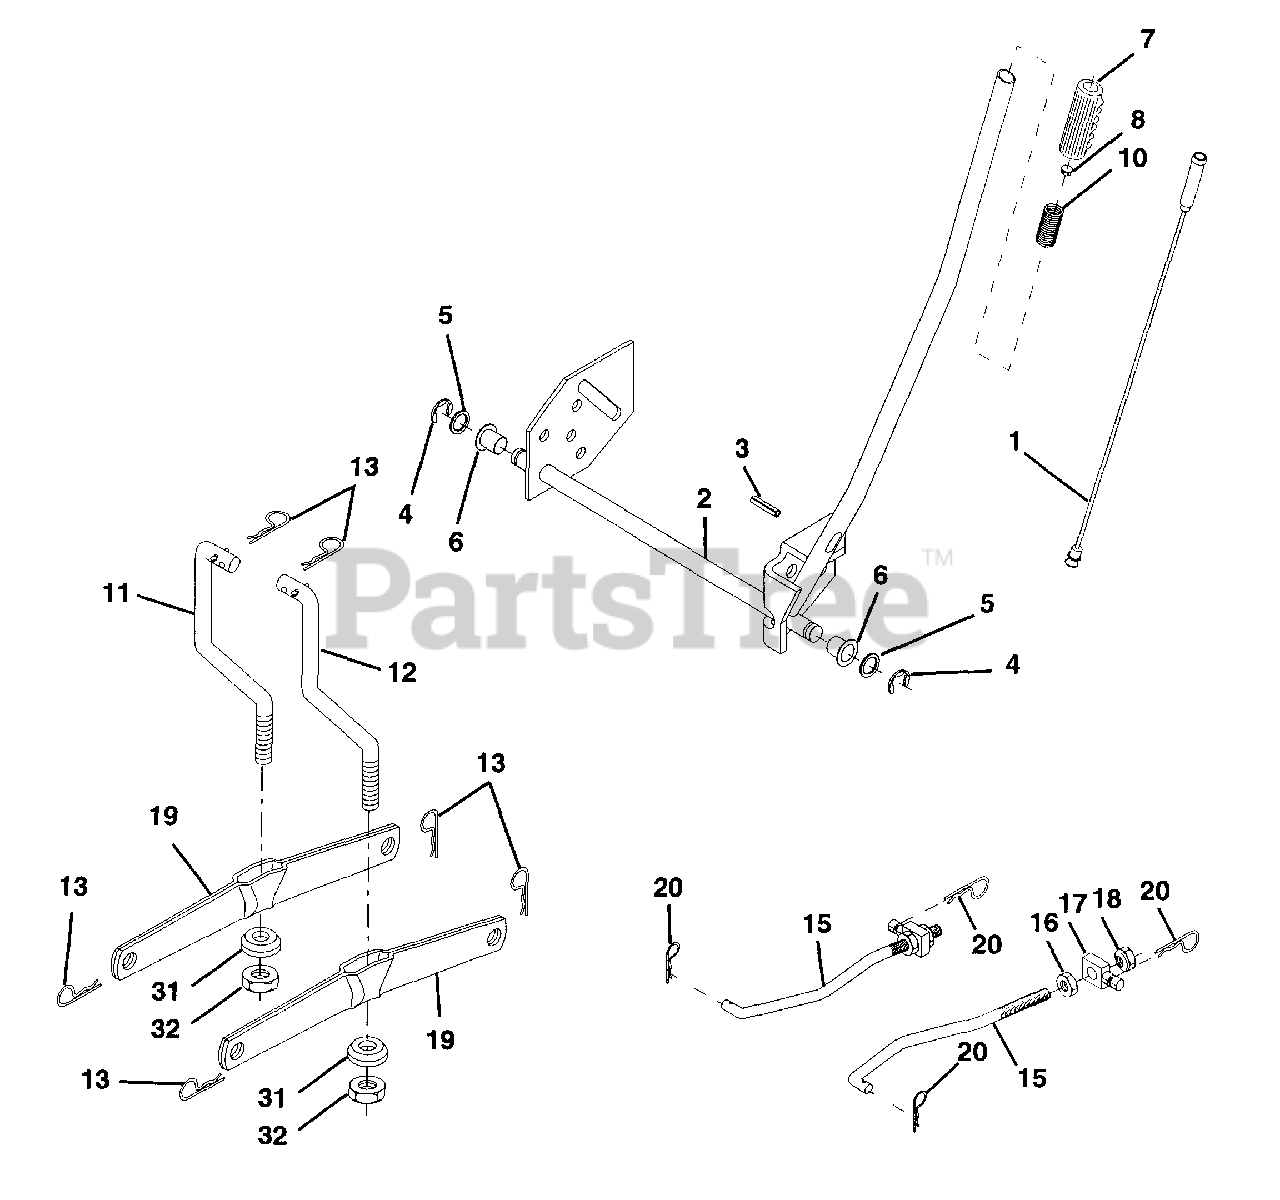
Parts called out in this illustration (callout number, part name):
1	Wire Asm Inner W/plunger 17 32
2	Shaft Asm Lift
3	Pin Groove
4	E Ring #5133-62
5	Washer PLTD 21/32 X 1 X 21 ga
6	Bearing Nylon Blk 629 Id
7	Grip Handle Bicycle
8	Button Plunger Black
10	Spring Cprsn 3 750 Oiled
11	Link Lift LH
12	Link Lift RH
13	Retainer Spring
15	Link Front
16	Nut Jam Hex 1/2-13 Unc
17	Trunnion Blk Zinc
18	Nut Lock W/wsh 1/2-13 unc
19	Arm Suspension Rear
20	Spring, Retainer
31	Bearing Pvt. Lift Spherical
32	Nut Crownlock 3/8-24
